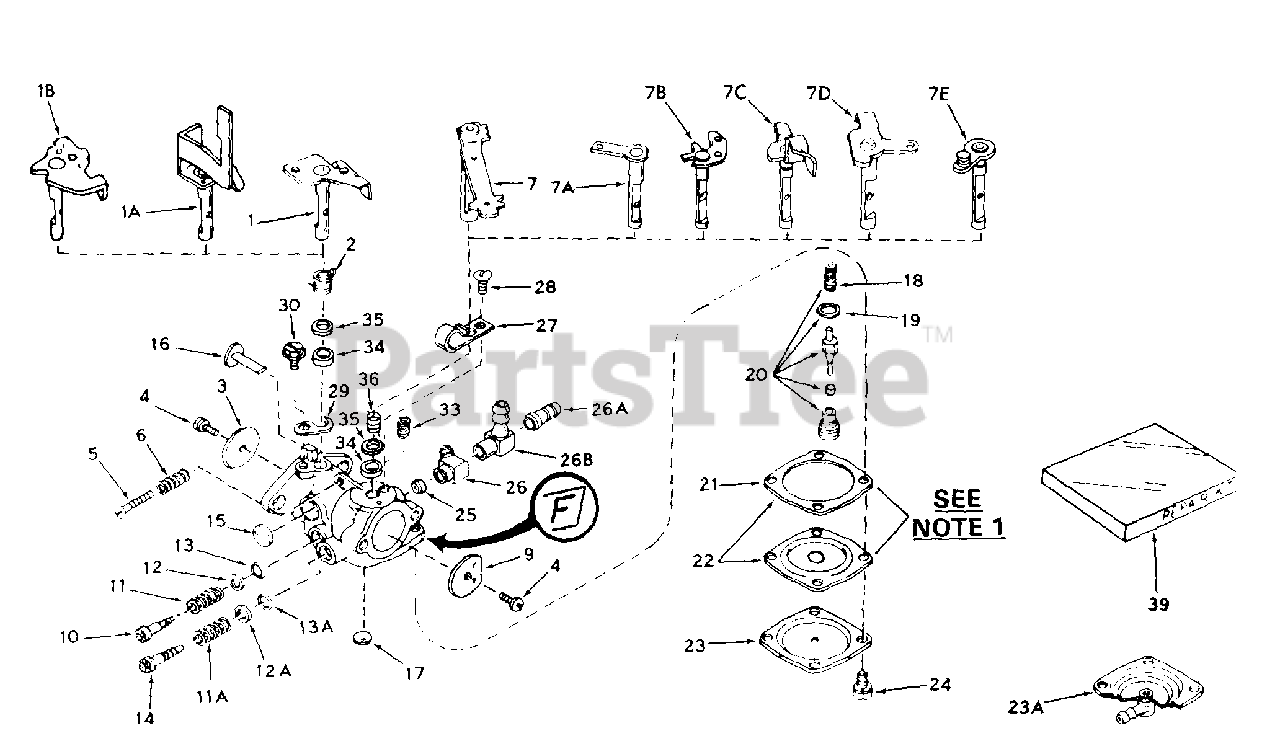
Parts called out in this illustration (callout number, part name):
1	"Shaft & Lever Assy., Throttle
2	Spring, Throttle return
3	Shutter, Throttle
4	Screw, Throttle & Choke shutter
5	Screw, Idle reg.
6	Spring, Idle reg. screw
7A	Shaft & Lever Assy., Choke
9	Shutter, Choke
10	Screw, Idle adj.
11	Spring, Adj. screw
11A	Spring, Adj. screw
12	Washer, Adj. screw
12A	Washer, Adj. screw
13	"O" Ring, Adj. screw
13A	"O" Ring, Adj. screw
14	Screw, Main adj. (.0225 dia. hole)
15	Plug, Welch
16	Element, Pump
17	Plug, Welch
18	Spring, Valve
19	Gasket, Valve seat
20	Inlet Needle, Seat, Gasket & Spring
21	Gasket, Diaphragm
22	Diaphragm Assy.
23	Cover, Diaphragm
24	Screw, Cover
25	Valve, Check
26	Fitting, Fuel inlet
27	Spring, Detent
29	Retainer, Throttle shaft
39	Repair Kit
